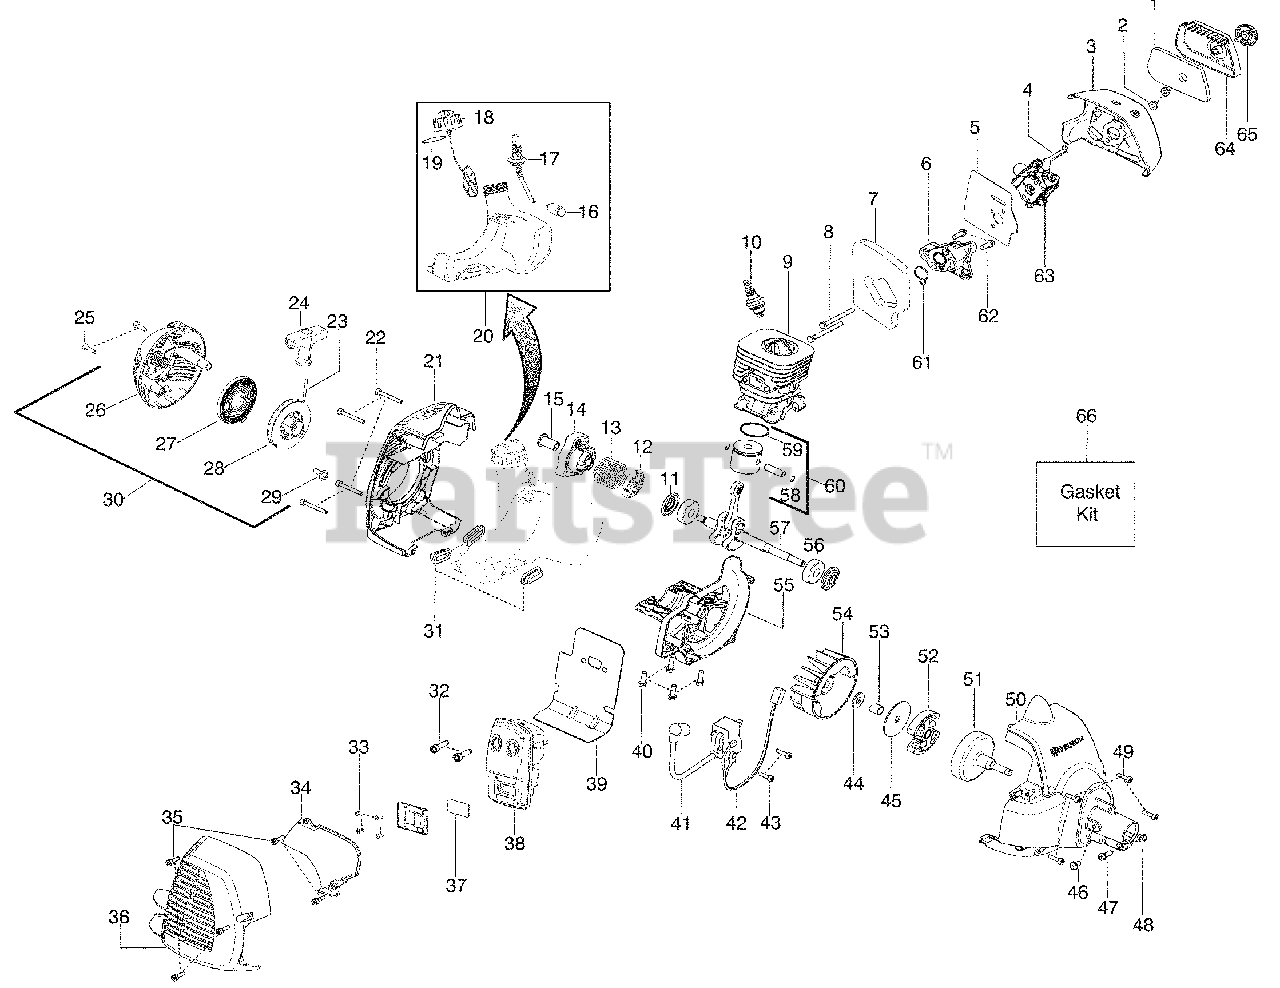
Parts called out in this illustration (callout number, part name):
2	Nut-Carb. Screw
3	Air Box
4	Lever - Choke
5	Kit-Carb. Gasket
6	Adaptor-Carb.
7	Kit-Gasket
9	Cylinder
10	Plug-Spark (RCJ-6Y)
11	Kit-Crankshaft seal
12	Washer-Starter
13	Spring-Starter Cup
14	Assy-Starter Cup
15	Coupling-Starter
16	Assy-Fuel Filter
17	Kit-Fuel Line
18	Assy-Cap w/ret.
19	Kit Gasket O-ring - Fuel Cap
20	Assy-Fuel Tank
21	Shroud-Rear
24	Handle-Starter
25	Screw
26	Starter Hsg. w/eyelet
27	Kit-Starter Spring
28	Kit-Starter Pulley
30	Assy-Starter Hsg.
31	Isolator-Tank
32	Bolt-Muffler
34	Shield-Heat
36	Guard-Muffler
37	Kit-Spark Arrestor
38	Assy-Muffler
39	Kit-Gasket-Paper met.
41	Module
42	Assy-Leadwire
45	Washer-Clutch
50	Assy-Fan Housing
51	Assy-Clutch Drum
52	Kit-Clutch Assy.
55	Crankcase
57	Kit-Crankshaft
58	Retainer-Piston Pin
59	Ring-Piston
60	Kit-Piston
61	Kit-Gasket
63	Kit-Carb.
64	Cover-Air Box
66	Kit-Gasket
